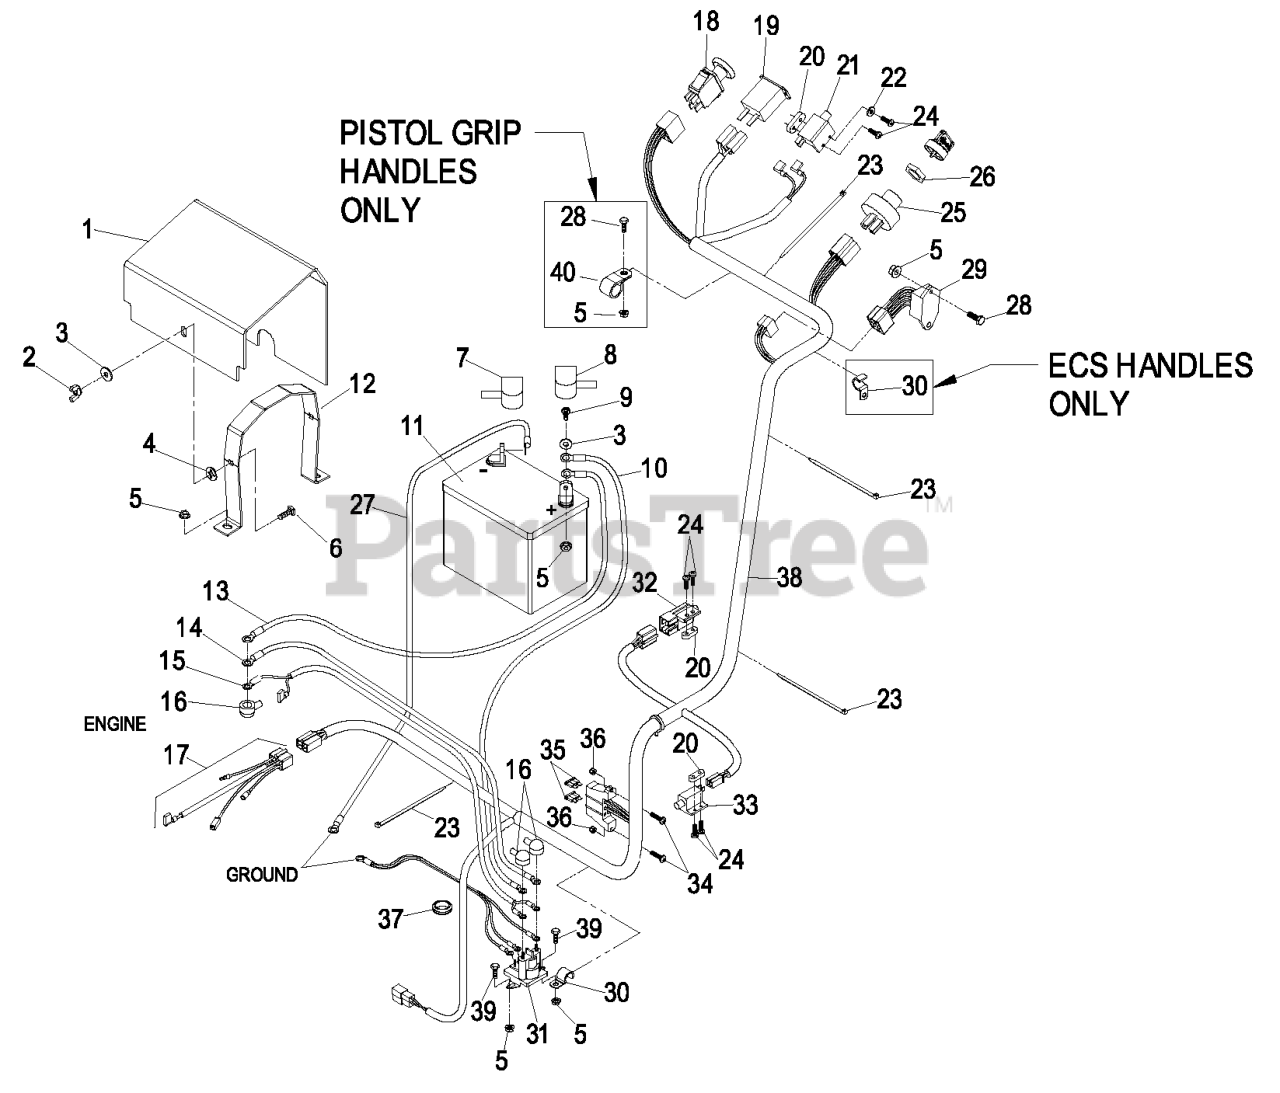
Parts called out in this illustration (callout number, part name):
1	COVER,BATTERY W/DECAL
2	NUT-WING
3	WASHER-FLAT
4	NUT-RETAINING
6	BOLT-CARR
7	INSULATOR, BATTERY -
9	SCREW-HH
12	STRAP,BATTERY HOLDDOWN
16	INSULATOR-SOLENOID
17	HARNESS,WIRING 19KA
19	METER-HOUR
20	PLATE-TAPPED
21	SWITCH-OPEN, NORMALLY
22	WASHER-FLAT
23	TIE-PLASTIC
24	SCREW-PPH
25	SWITCH,IGNITION
26	NUT-SWITCH, IGNITION
27	WIRE-GROUND
28	SCREW-HH
29	MODULE-OPC NO TIME DELAY
30	CLIP-HALF, LOOM
33	SWITCH-CLOSED, NORMALLY
34	SCREW-HEAD, TRUSS
35	FUSE-BLADE TYPE, 20 AMP
36	NUT-LOCK, NI
37	GROMMET
39	SCREW-HH
40	CLIP-LOOM
